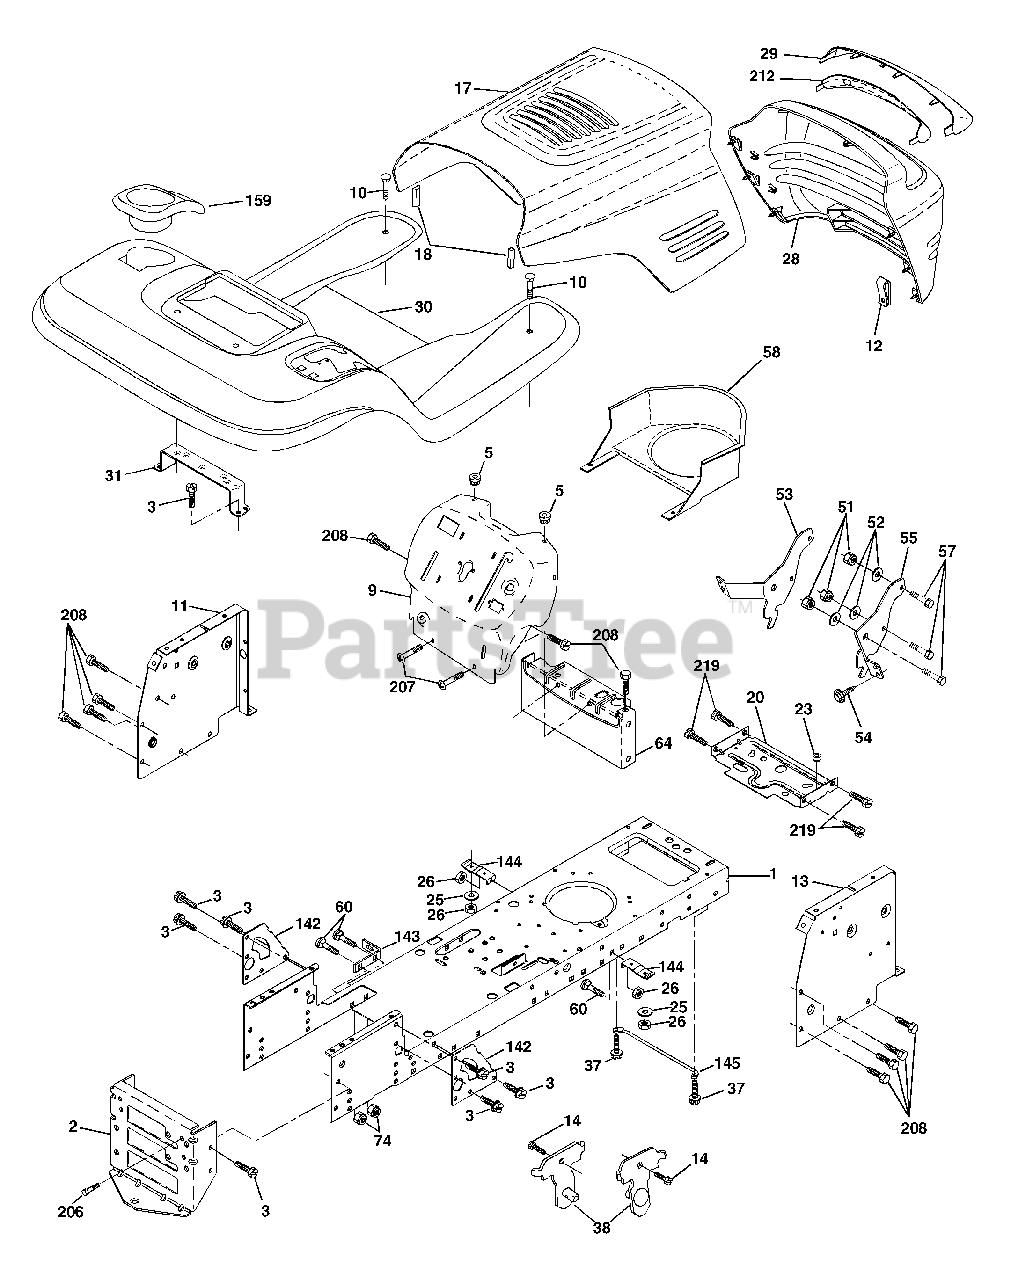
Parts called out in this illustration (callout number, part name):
1	Chassis Stamping
3	Screw 3/8-16x3/4
9	Dashboard
10	Bolt Rdhd Sqnk 3/8-16 Unc x 1
11	Panel Dash Lh
12	Clip Tinnerman Grille
13	Panel Dash Rh
14	Screw Thdrol 3/8-16 x 1/2
17	Hood
20	Plate Mtg Battery/Fuel Tank
25	Washer 13/32 x 13/16 x 12 Ga.
26	Nut Lock w/Insert 3/8-16 UNC
28	Grille Lens Asm
29	Lens
30	Fender
37	Screw Thdrol 5/16-18 x 1/2
38	Bracket Asm Pivot Mower Rear
51	Nut Lock w/Insert 1/4-20
52	Washer 9/32 x 7/8 x 16 Ga.
53	Bracket Grille Lh
54	Screw Hex Wshd 8-18 x 7/8
55	Bracket Grille Rh
57	Bolt Fin Hex 1/4-20 Unc x 3/4
60	Bolt RDHD SQNK 3/8-16 x 3/4
64	Dash Lower Stlt
74	Nut Crownlock 3/8-16
142	Plate Reinforcement
143	Bracket Swaybar Chassis
144	Bracket Ft Rest
145	Rod Pivot Chassis Hood
159	Cupholder YTGT Grey
206	Bolt Shoulder 5/16-18 TT
207	Screw Thdrol 5/16-18 x 1/2 TYTT
208	Screw Thdrol 3/8-16 x 1/2 Ty-TT
212	Insert Lens Reflect
